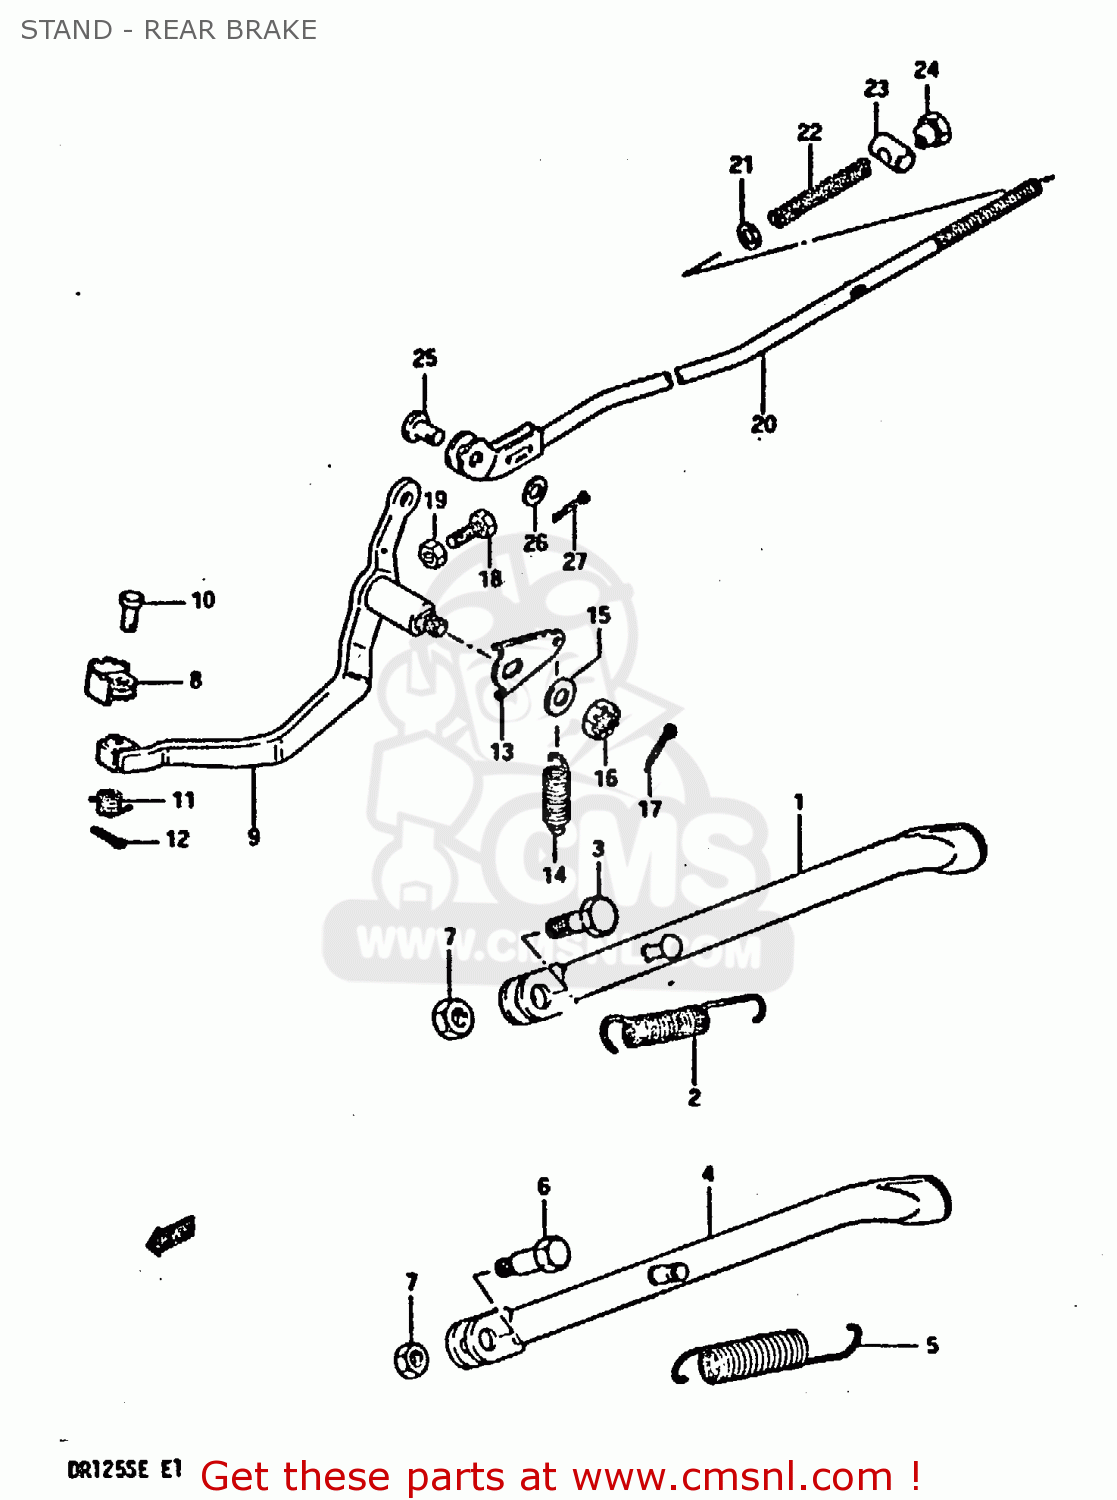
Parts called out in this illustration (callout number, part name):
1	STAND,SIDE
2	SPRING
3	BOLT(10X30)
4	STAND, PROP (BLUE)
5	SPRING
6	BOLT L:30
7	NUT
8	PEDAL,BRAKE
9	ARM,BRAKE PEDAL
10	PIN
11	SPRING
12	PIN
13	ARM,BRAKE RETURN SPRING
14	SPRING
15	WASHER
16	NUT
17	PIN 20X20
18	BOLT(6X23)
19	NUT
20	ROD ASSEMBLY,REAR BRAKE
21	WASHER
22	SPRING
23	PIN
24	NUT (6MM)
25	PIN
26	WASHER
27	PIN 20X20
